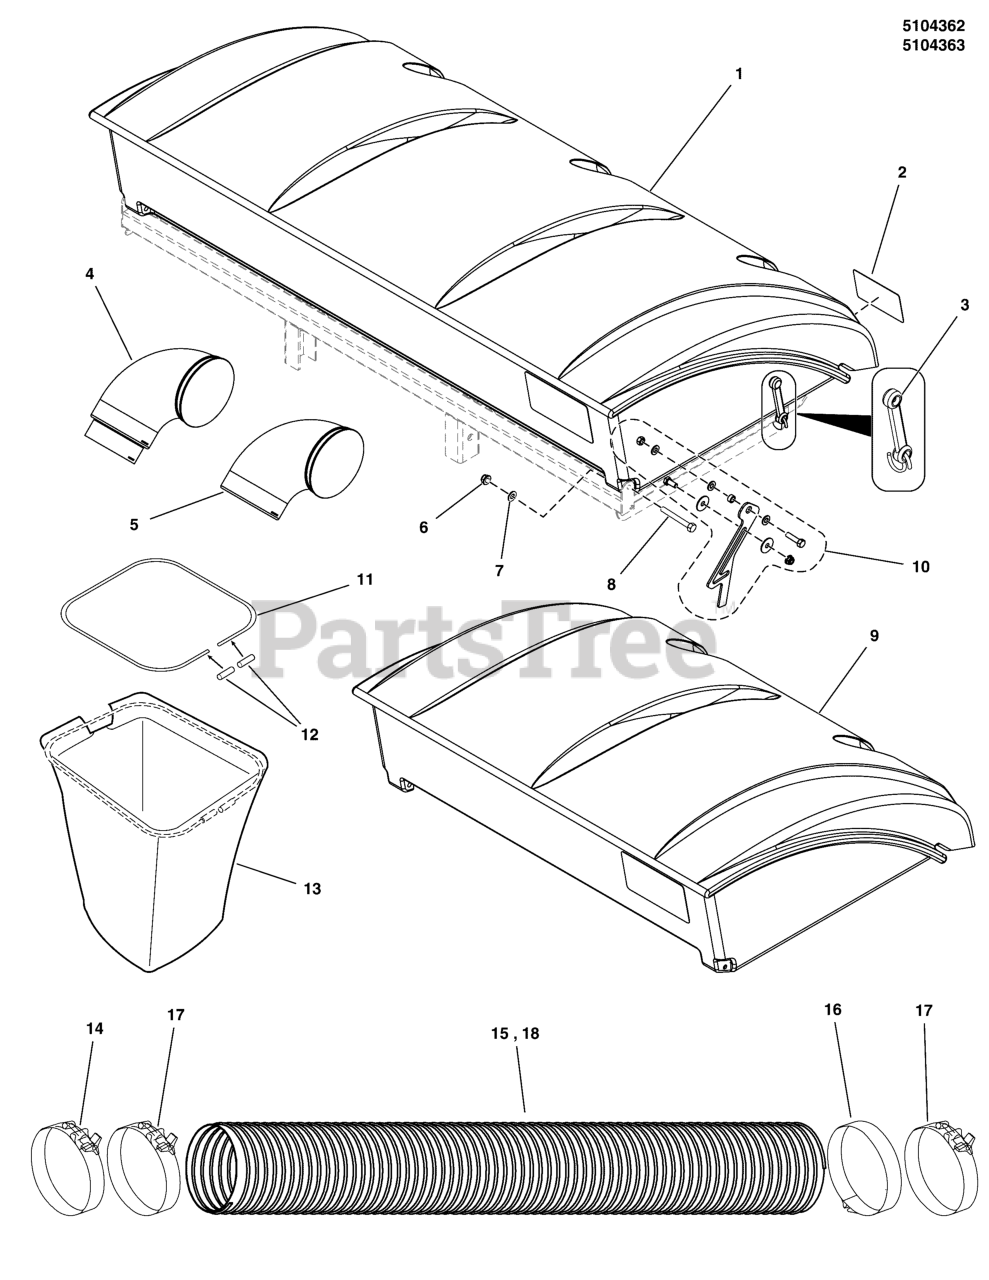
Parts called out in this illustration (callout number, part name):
1	TOP ASSEMBLY / P3B / FERRIS - NET
2	RED REFLECTOR DECAL - NET
3	RUBBER STRAP W/HOOKS - NET
4	P2B INLET / 6 INCH / CUT
5	P2B INLET / 6 INCH / CUT
6	NUT, Hex Flange, Nylock, 1/2-13
7	WASHER, 1/2 SAE
8	BOLT, 1/2-13 X 2-1/2" GD5 CZ
9	TOP ASSEMBLY / P2B+ / FERRIS - NET
10	VAC KIT HW / P3B / FERRIS - NET
11	PART B0227 BAG RING / GENERIC - NET
12	PART J0274 VINYL CAP - NET
13	BAG COLLECTION SYSTEM SMALL
14	CLAMP, HOSE, LOWER
15	HOSE, FLEXIBLE, 7" DIA. X 58"
16	CLAMP, HOSE, UPPER
17	CLAMP, 6" UPPER & LOWER, COLLECTORS
18	HOSE, FLEXIBLE, 6" DIA X 54"
